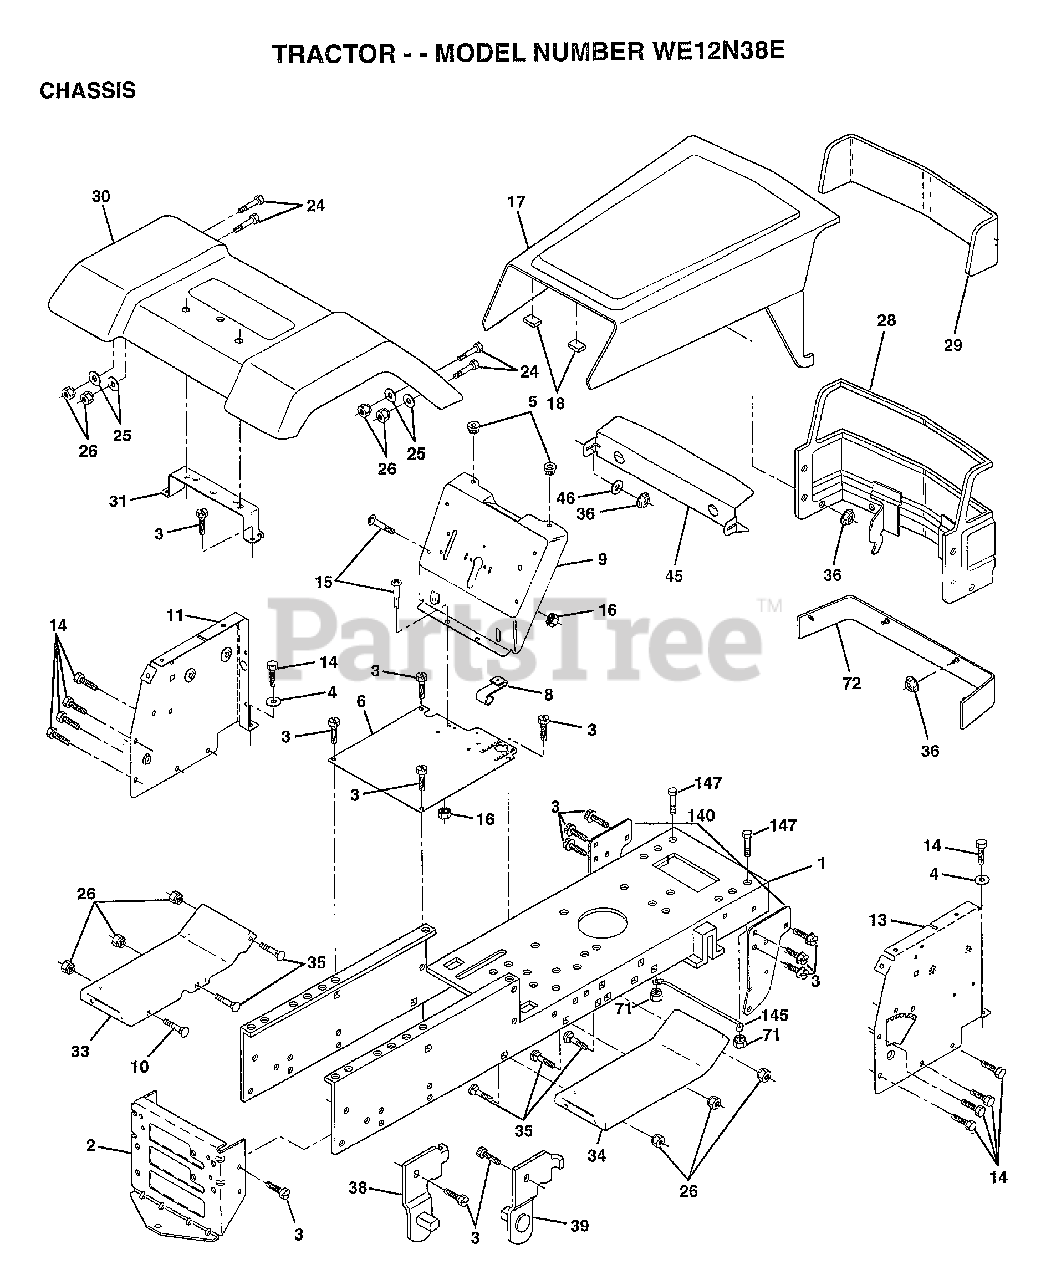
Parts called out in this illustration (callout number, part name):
1	CHASSIS ASM
3	SCREW
4	WASHER
5	BUMPER-HOOD/DASH
6	SADDLE-SILKSCREEN
8	CLIP.RETAINER
9	DASH SILKSCR
11	"PANEL-DASH,LH"
14	SCREW LT
15	SCREW
17	HOOD.W/SD.PNLS.LT
24	BOLT
25	WASHER
26	NUT
28	GRILLE.RALLY.BAR.
29	LENS SERVICE KIT
31	BRKT FENDER
33	FOOTREST.LH.PERF.
34	FOOTREST.RH.PERF.
35	BOLT
36	PAL NUT LT
38	BRACKET ASM LH
39	BRACKET ASM RH
46	RETAINER
140	BRKT SUSPENSION
145	"ROD POVOT,CHASSIS"
147	BOLT LT
